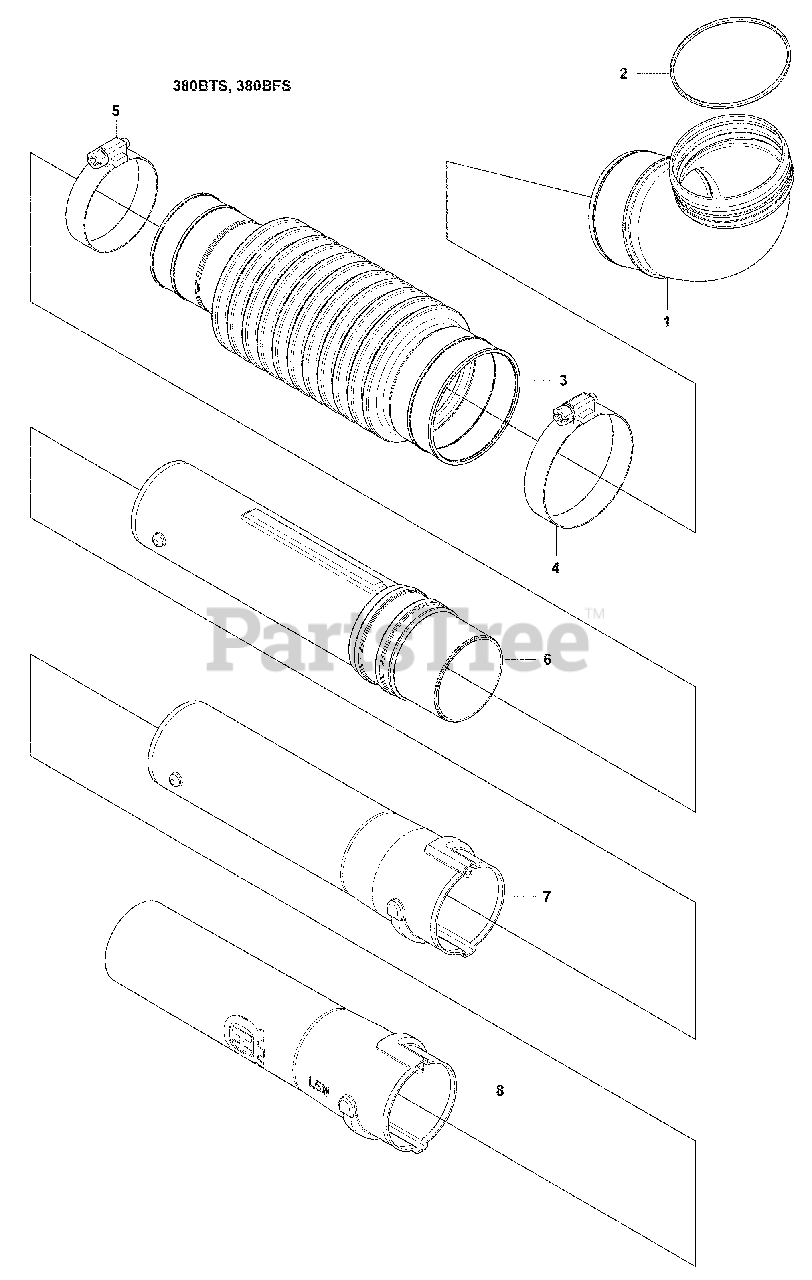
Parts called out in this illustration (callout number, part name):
4	Clamp, F115
5	Clamp, F96
6	Swivel Joint
7	Pipe
